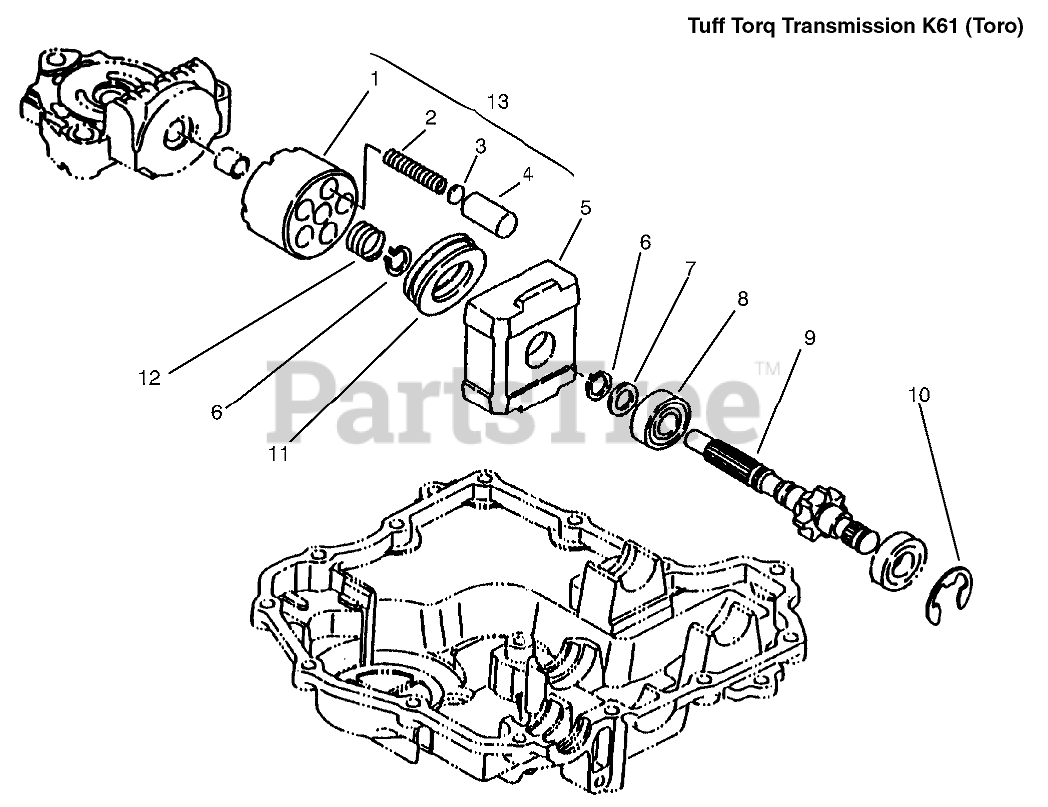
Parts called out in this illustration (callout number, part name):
1	Block-Cylinder
3	Washer
5	HOUSING
6	RING-SNAP
7	WASHER
8	BEARING-BALL
9	SHAFT - MOTOR
10	E-RING
11	BEARING-THRUST
13	ASM - CYCLINDER INC 6-9
